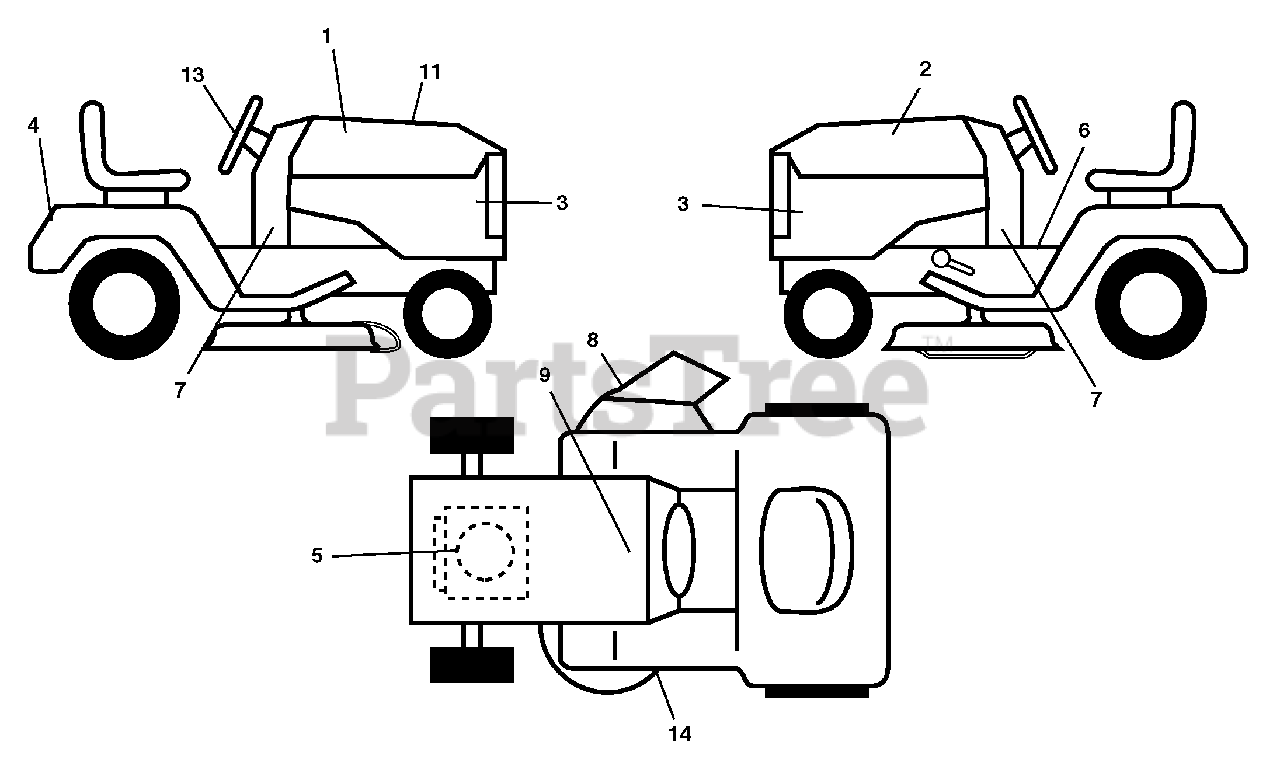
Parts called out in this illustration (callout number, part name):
1	Decal, Hood RH
2	Decal, Hood LH
3	Decal, Side Panel
4	Decal, Fender
5	Decal, Engine
6	Decal, Fender Operator's
7	Decal, Lower Dash
8	Decal, Warning
9	Decal, Battery Dnge/Poi
11	Decal, Replacement
13	Decal, Steering Wheel
14	Decal, Mower Schematic
